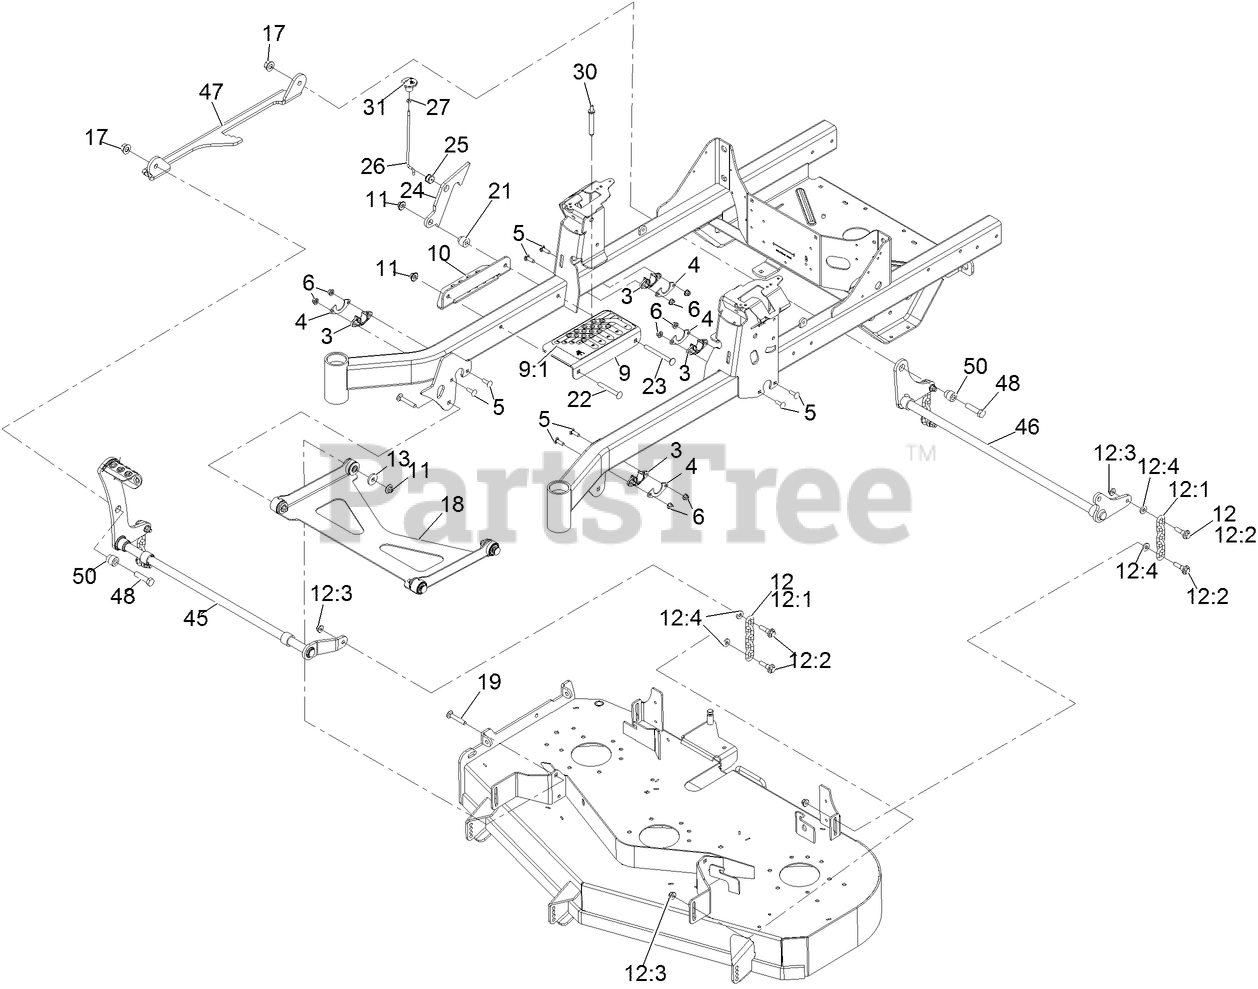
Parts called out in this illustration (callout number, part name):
3	BUSHING-FLANGE
4	GUSSET-LIFT, DECK
5	SCREW-CARR
6	NUT-HF, NI
9	BRACKET ASM
9:1	DECAL-HOC
10	ANGLE-HOC, LOWER
11	Nut-Nyloc 3/8-16 Flg
12	DECK CHAIN ASM
12:1	CHAIN-LIFT, DECK
12:2	BOLT-SHOULDER
12:3	NUT-HF, NI
17	Nut-Lock 1/2-13
18	DECK STRUT ASM
19	Bolt-Carriage 3/8-16 X 2 1/4
21	SPACER-STEPPED
22	SCREW-CARR
23	SCREW-CARR
24	PLATE-LOCK, TRANSPORT
25	GROMMET
26	ROD-LOCK, TRANSPORT
27	NUT-JAM
30	PIN-HOC
45	SHAFT-DECKLIFT FRONT
46	SHAFT-DECKLIFT REAR
47	LINK-DECKLIFT
48	SCREW-HH
50	Spacer-Stepped
